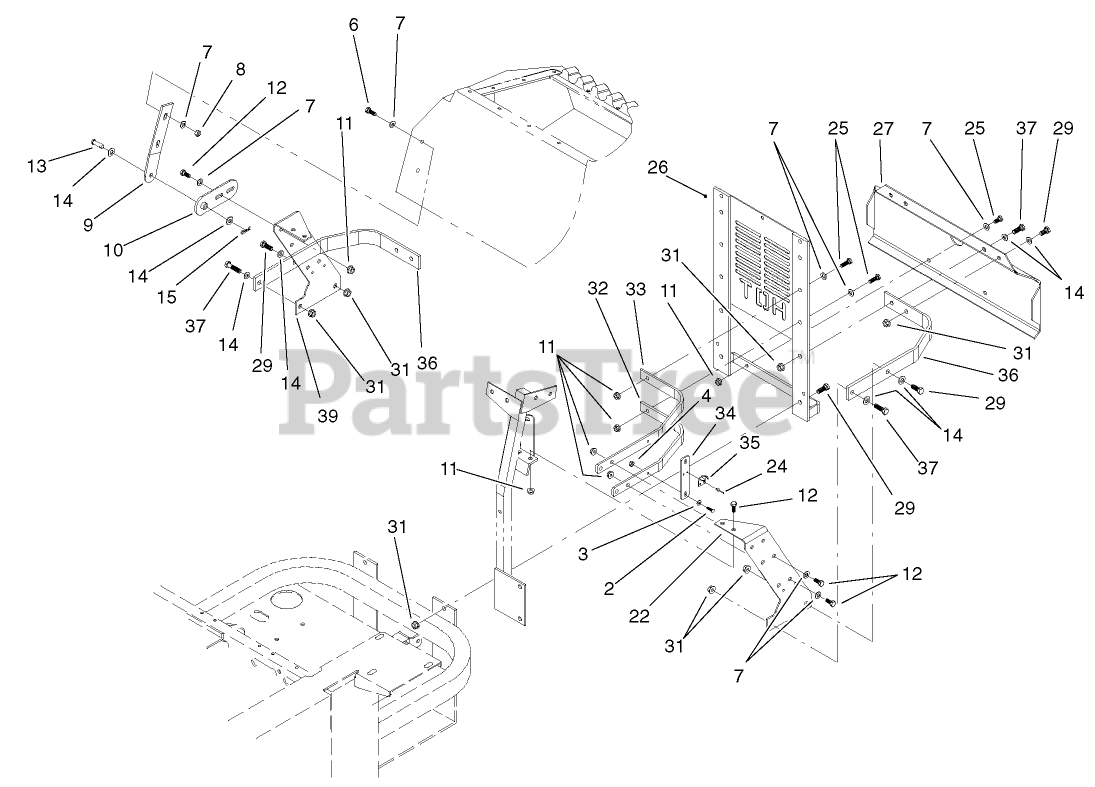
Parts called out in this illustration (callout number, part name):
2	SCREW
3	WASHER-FLAT
4	NUT-LOCK, NI
6	SCREW-HH
7	WASHER-PLAIN
8	NUT-LOCK, NI
9	PLATE-HINGE, HOOD
10	SHACKLE-HINGE
11	NUT-HF
12	SCREW-HH
13	PIN-CLEVIS
14	WASHER-FLAT
15	PIN-COTTER
22	PLATE-SIDE, LH
24	RIVET
25	SCREW-HH
26	MOUNT-RADIATOR, REAR
27	GUARD-BUMPER
29	SCREW-HH
31	NUT-HHF, WHIZ
33	RIB-BOTTOM
34	BAR-HOOK, LATCH
35	KEEPER-LATCH, RUBBER
36	BAR-RADIATOR MOUNT FRAME
37	SCREW-HH
39	PLATE-SIDE, RH
